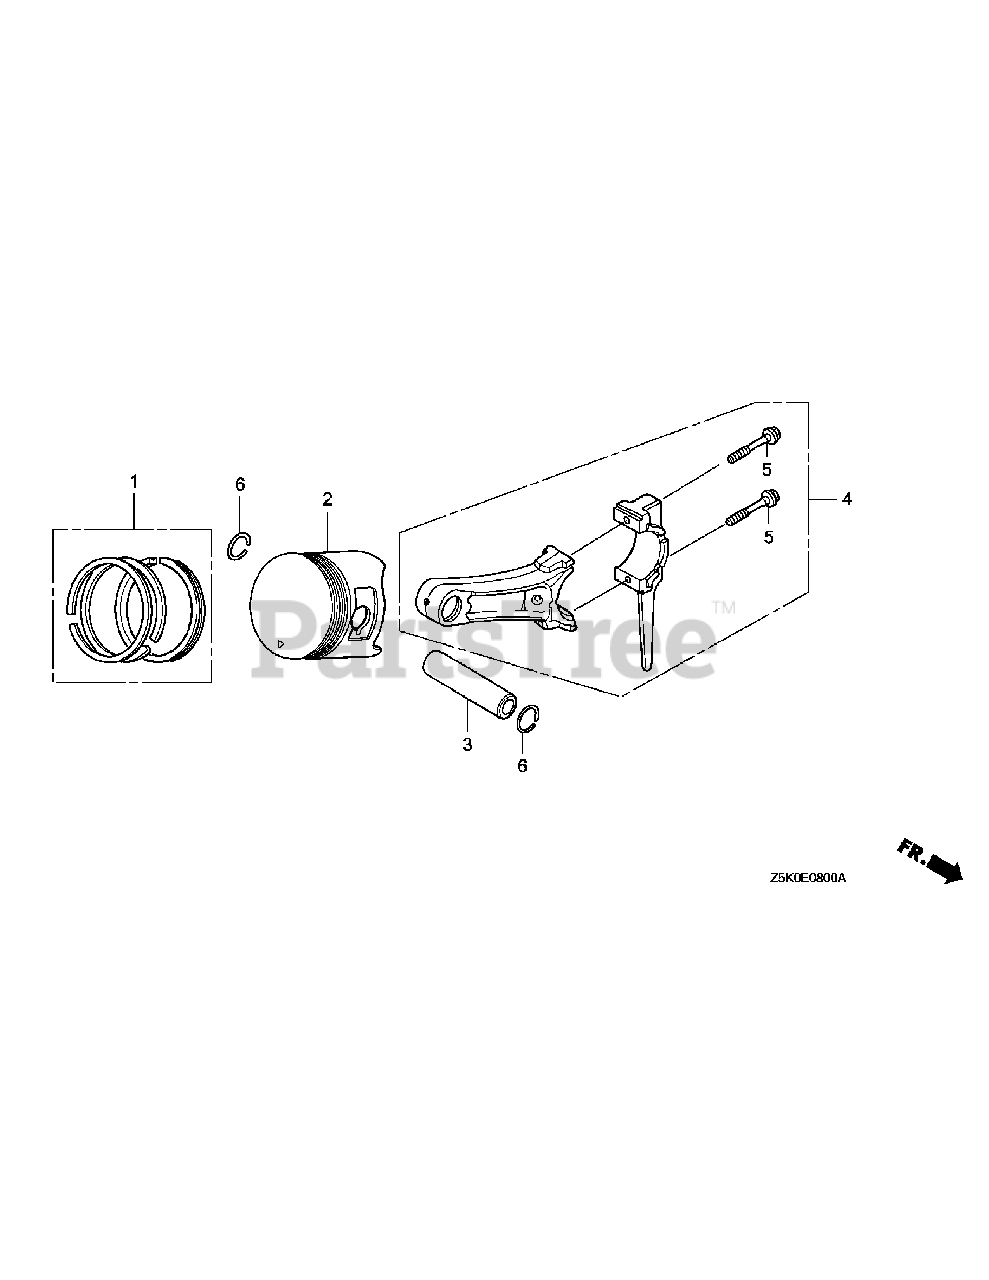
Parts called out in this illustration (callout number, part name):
1	Ring Set, Piston(Std.) (Teikoku)
1	Ring Set, Piston(0.25) (Teikoku)
1	Ring Set, Piston(0.50) (Teikoku)
1	Ring Set, Piston(0.75) (Teikoku)
2	Piston(Std.)
2	Piston(0.25)
2	Piston(0.50)
2	Piston(0.75)
3	Pin, Piston
4	Rod Assy., Connecting(Std.)
4	Rod Assy., Connecting (0.25 Under Size)
5	Bolt, Connecting Rod
6	Clip, Piston Pin, 18Mm
